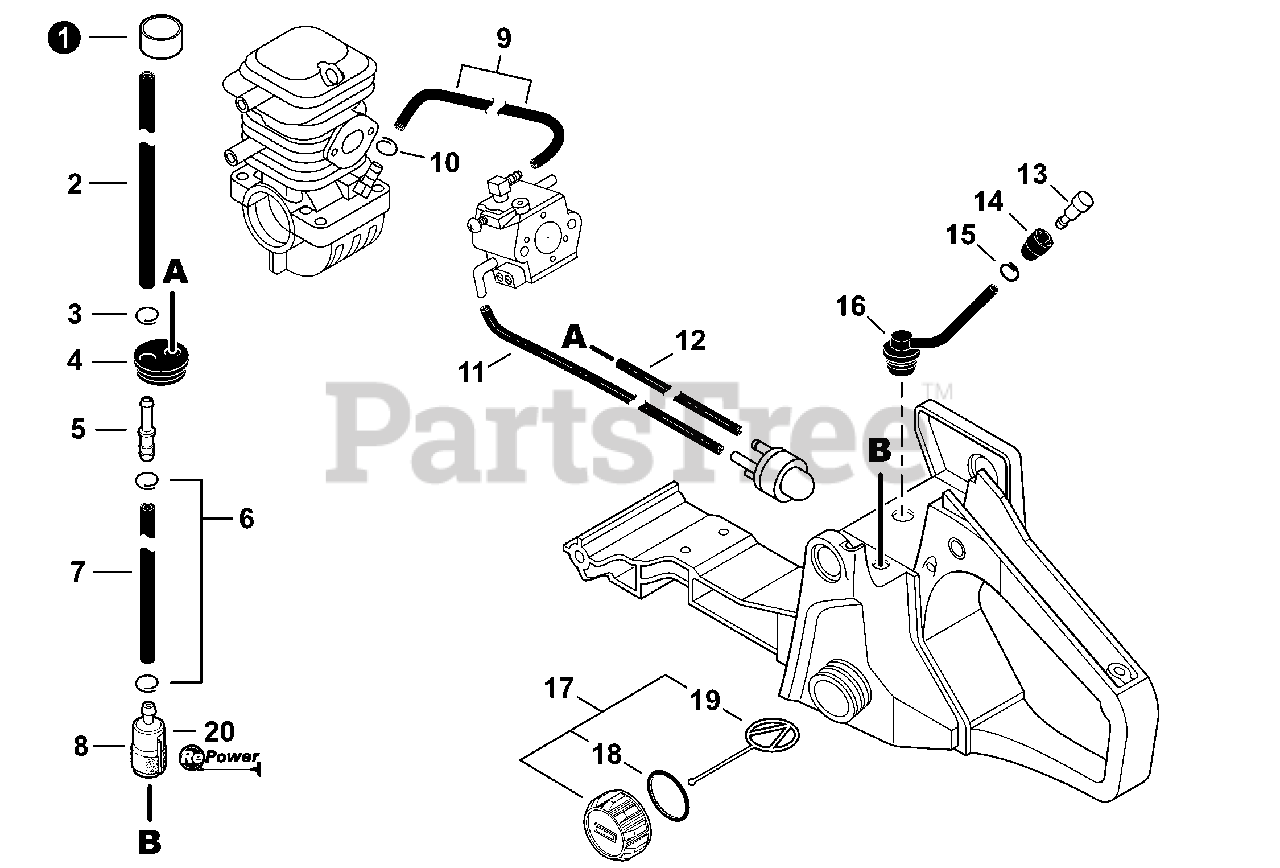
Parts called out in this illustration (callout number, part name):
1	TUBE 8×9×16
2	PIPE, FUEL - 3×5×182 - BLACK
4	GROMMET, FUEL
5	CONNECTOR, PIPE Ø5ר3.5
6	CLIP Ø6
7	PIPE, FUEL - 3×5×68 - BLACK
8	FILTER, FUEL
9	PIPE, PULSE 2.4×6×105
10	CLIP Ø6
11	PIPE 2.4×5×105 BLACK
12	PIPE, FUEL 2.4×5×200 BLACK
13	VENT ASSY
14	HOLDER, VENT
15	CLIP Ø6.5 MM
16	PIPE, VENT 3×6×65
17	CAP ASSY, FUEL
18	O-RING 22
19	CONNECTOR, CAP L= 60 MM
20	TUNE-UP KIT - REPOWER
